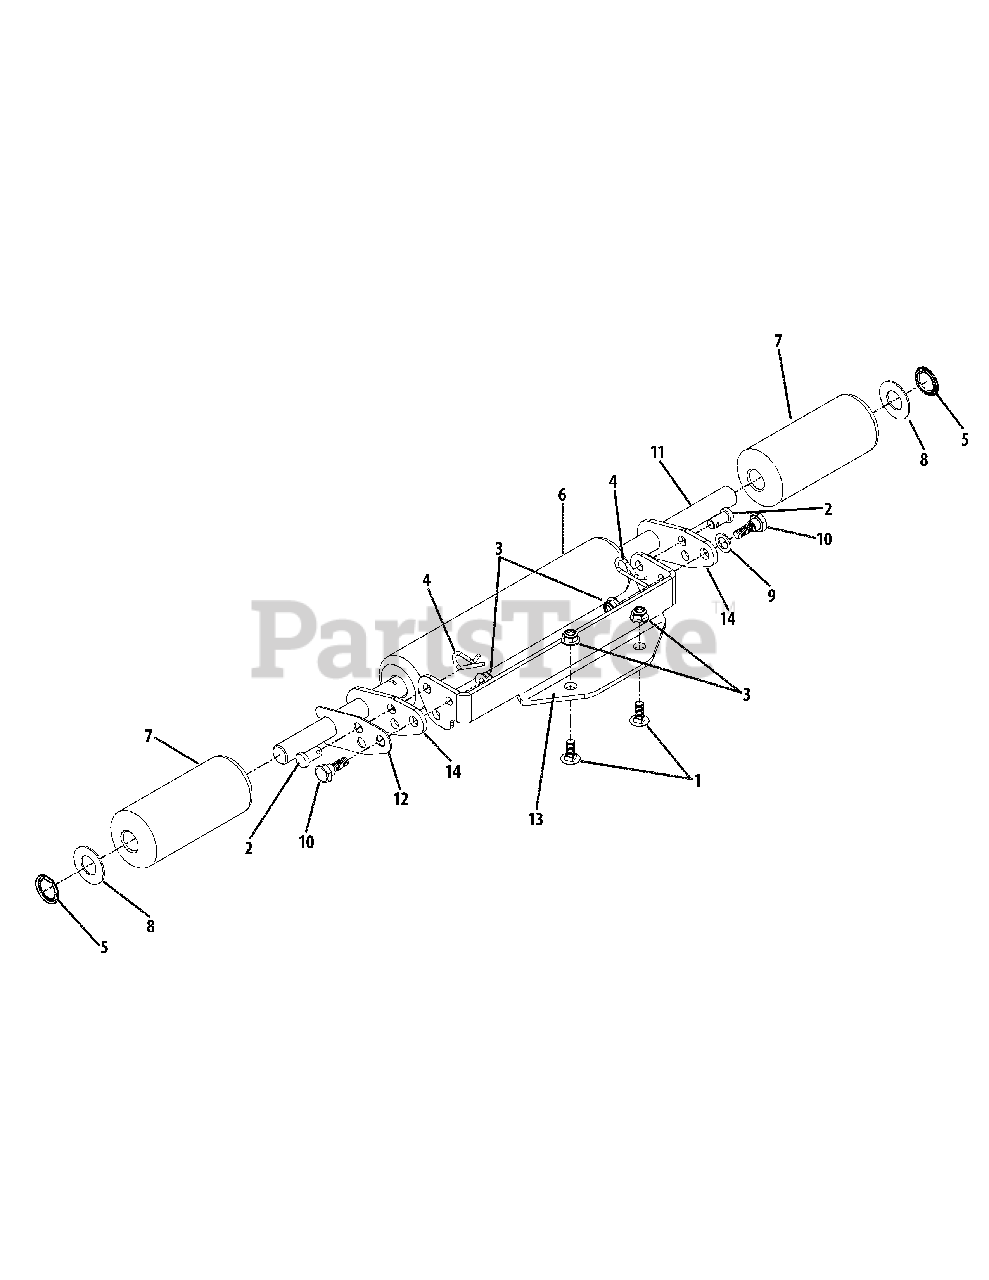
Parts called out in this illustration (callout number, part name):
1	Carriage Bolt, 5/16-18 x .750
2	Clevis Pin, 3/8 x .750
3	Flange Lock Nut, 5/16-18
4	Cotter Pin
5	Push Nut, 3/4
6	Deck Roller
7	Deck Roller, 2.25 x 5.25
8	Flat Washer, .76 x 1.49 x .06
9	Flat Washer, .469 x .750 x .06
10	Shoulder Screw, .437 x .268 x 5/16-18
11	Roller Rod, .75 x 22.875
